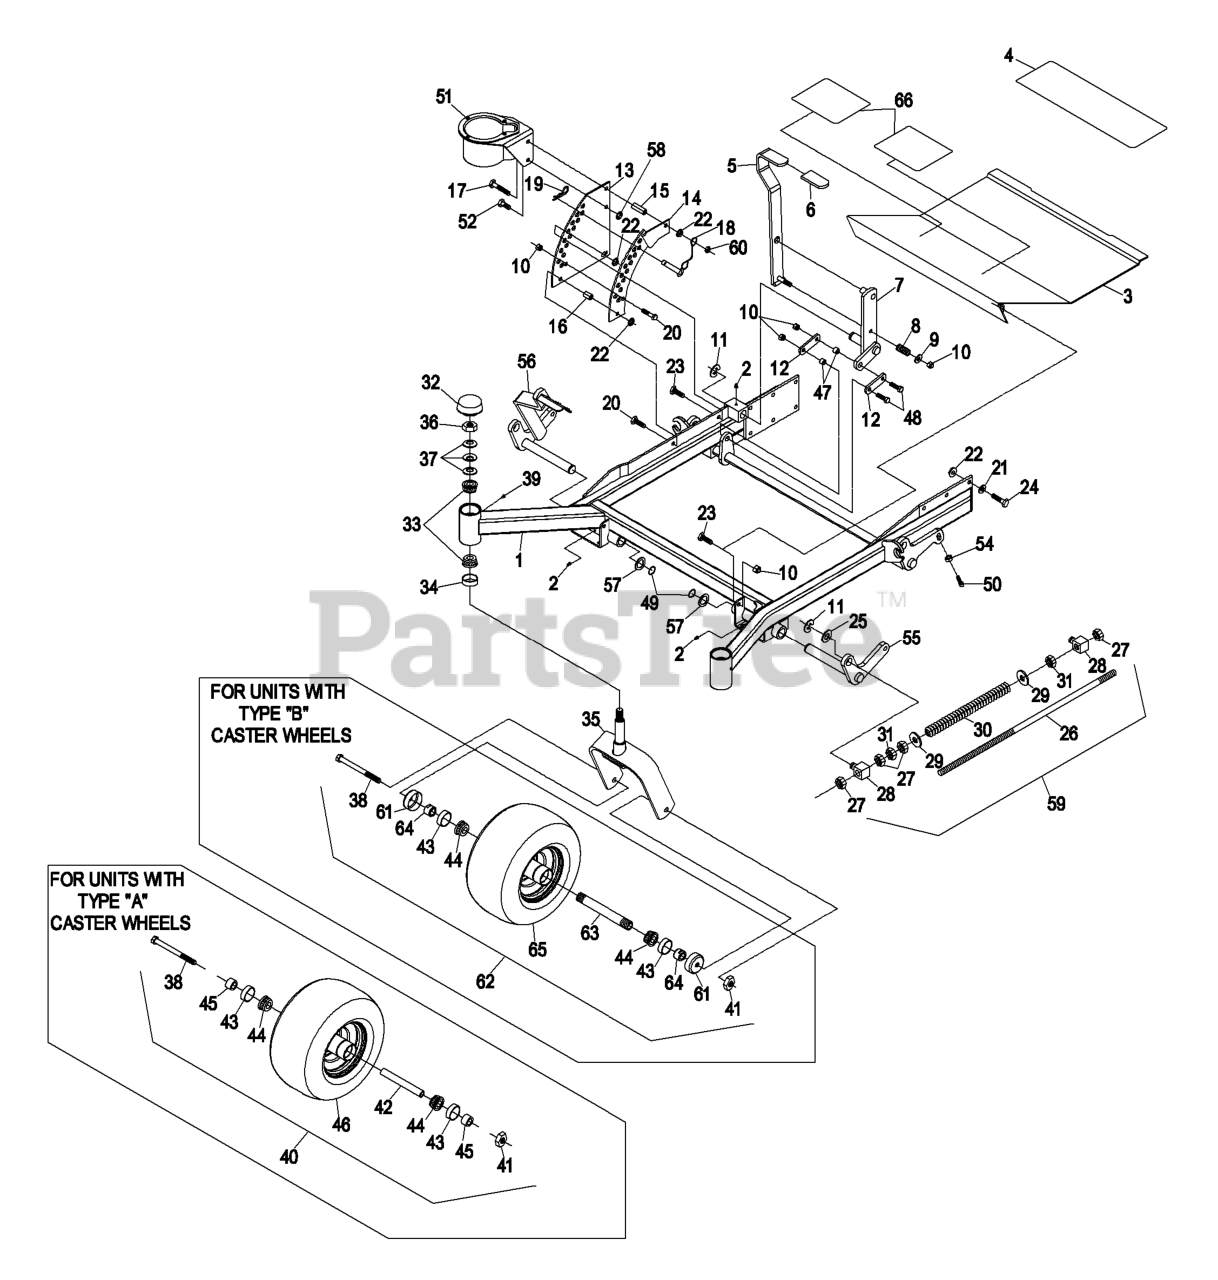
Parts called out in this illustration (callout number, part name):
2	FITTING-GREASE
3	ASM,FLOORPAN W/PADS
4	PAD-ANTISKID
5	LIFT LEVER/GRIP ASM
6	GRIP-LEVER, LIFT
7	ARM-LIFT, DECK
8	SPRING-COMPRESSION
9	WASHER-FLAT
10	NUT-LOCK, NI
11	RING-RETAINING, EXT
12	ARM-LIFT, DECK
13	PLATE-LIFT, DECK
14	PLATE-LIFT, DECK
15	BUSHING-LEVER, LIFT
16	BUSHING-LEVER, LIFT
17	SCREW-HH
18	PIN-HITCH (W/LANYARD)
19	PIN-COTTER
20	SCREW-HH
21	WASHER-BELLEVILLE
22	NUT-HHF, WHIZ
23	SCREW-HH
24	SCREW-HH
25	WASHER-FLAT
26	ROD-LIFT, DECK
27	NUT-HEX
28	SWIVEL-DECK MOUNT, REAR
29	WASHER-FLAT
30	SPRING-SUPPORT, DECK
31	NUT-JAM
32	CAP-GREASE
33	Cone-Bearing Tapered Roller
34	SEAL-GREASE
36	NUT-LOCK, NI
37	WASHER-BELLVILLE
38	SCREW-HH
41	NUT-LOCK, NI
42	SPACER-CASTER, FRONT
43	SEAL-CASTER
44	BEARING-CONE, TAPERED ROLLER
45	SPACER-BEARING
47	BUSHING
48	SCREW-HH
49	RING-RETAINING
50	SCREW-HSH
52	SCREW-HH
54	NUT-JAM
55	WLD, FRONT LIFT SHAFT - L
56	WLD, FRONT LIFT W/ LEVER
57	WASHER-SPACER
59	FRONT FRAME SPRING ASM
61	GUARD-SEAL
64	SPACER-NUT
66	PAD-ANTI SKID
